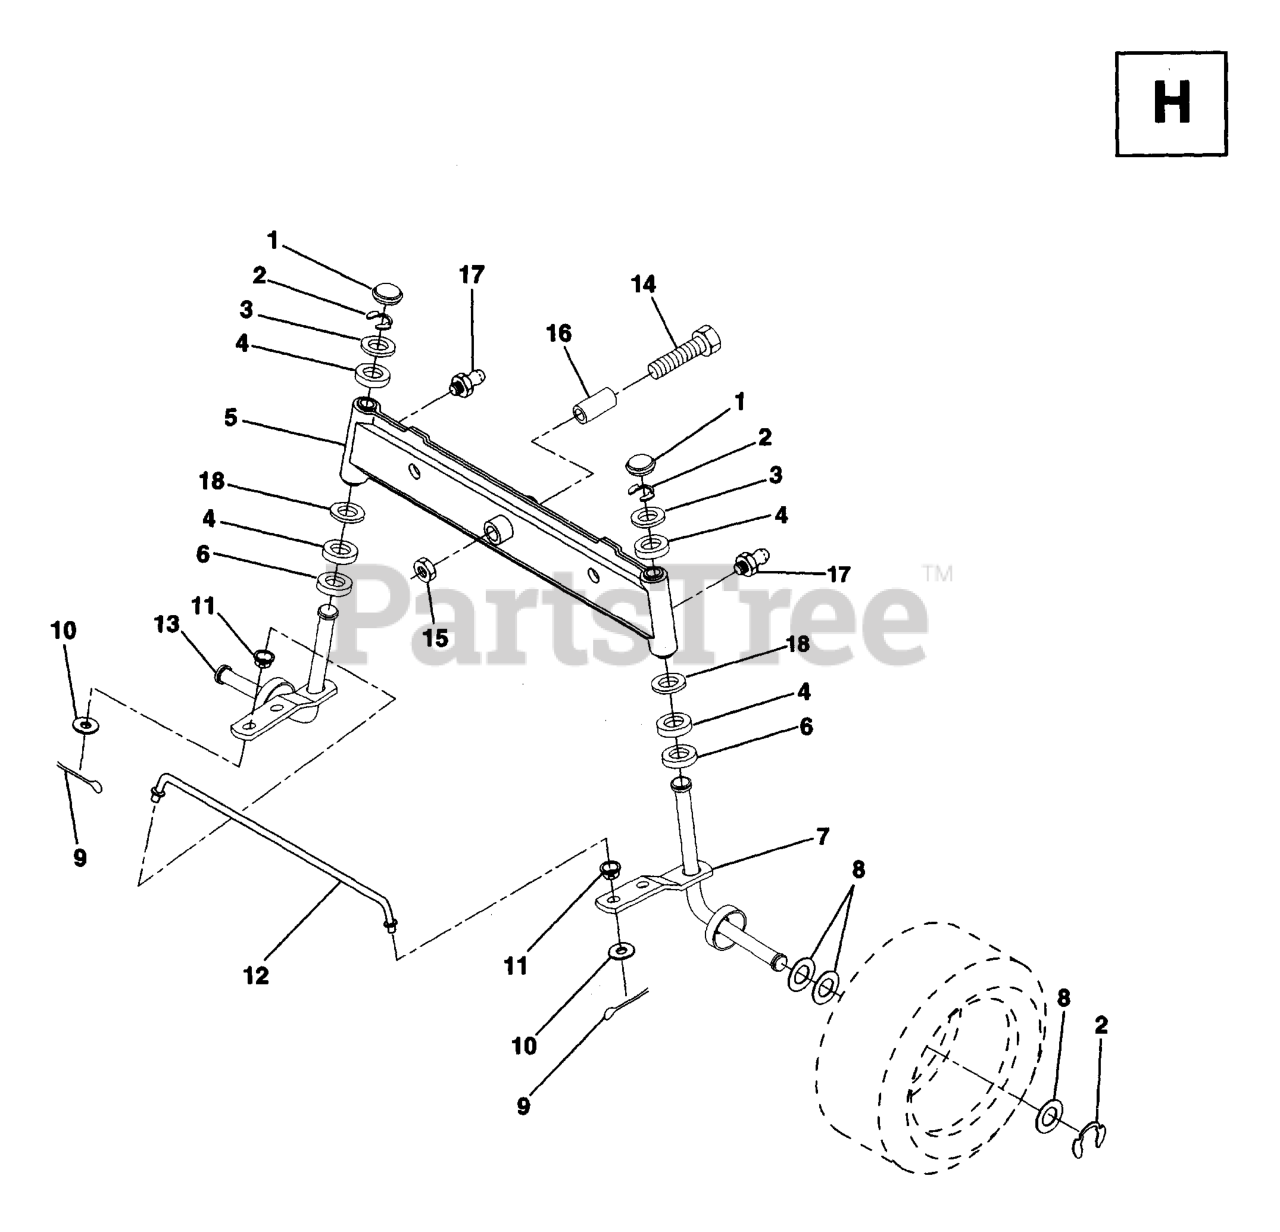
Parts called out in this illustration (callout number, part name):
1	CAP.SPINDLE.BLACK
4	BRNG T
6	THRUST WASHER
7	SPINDLE ASSY RH NLA
9	COTTER PIN
10	WASHER
11	BUSHING.DRAGLINK (2 2)
12	TIE ROD
13	SPINDLE ASSY LH
14	Bolt, Hex Head 5/8-11 x 3-1/2
15	NUT-LOC,FLANGE LT
16	BEARING
17	ZERK M
